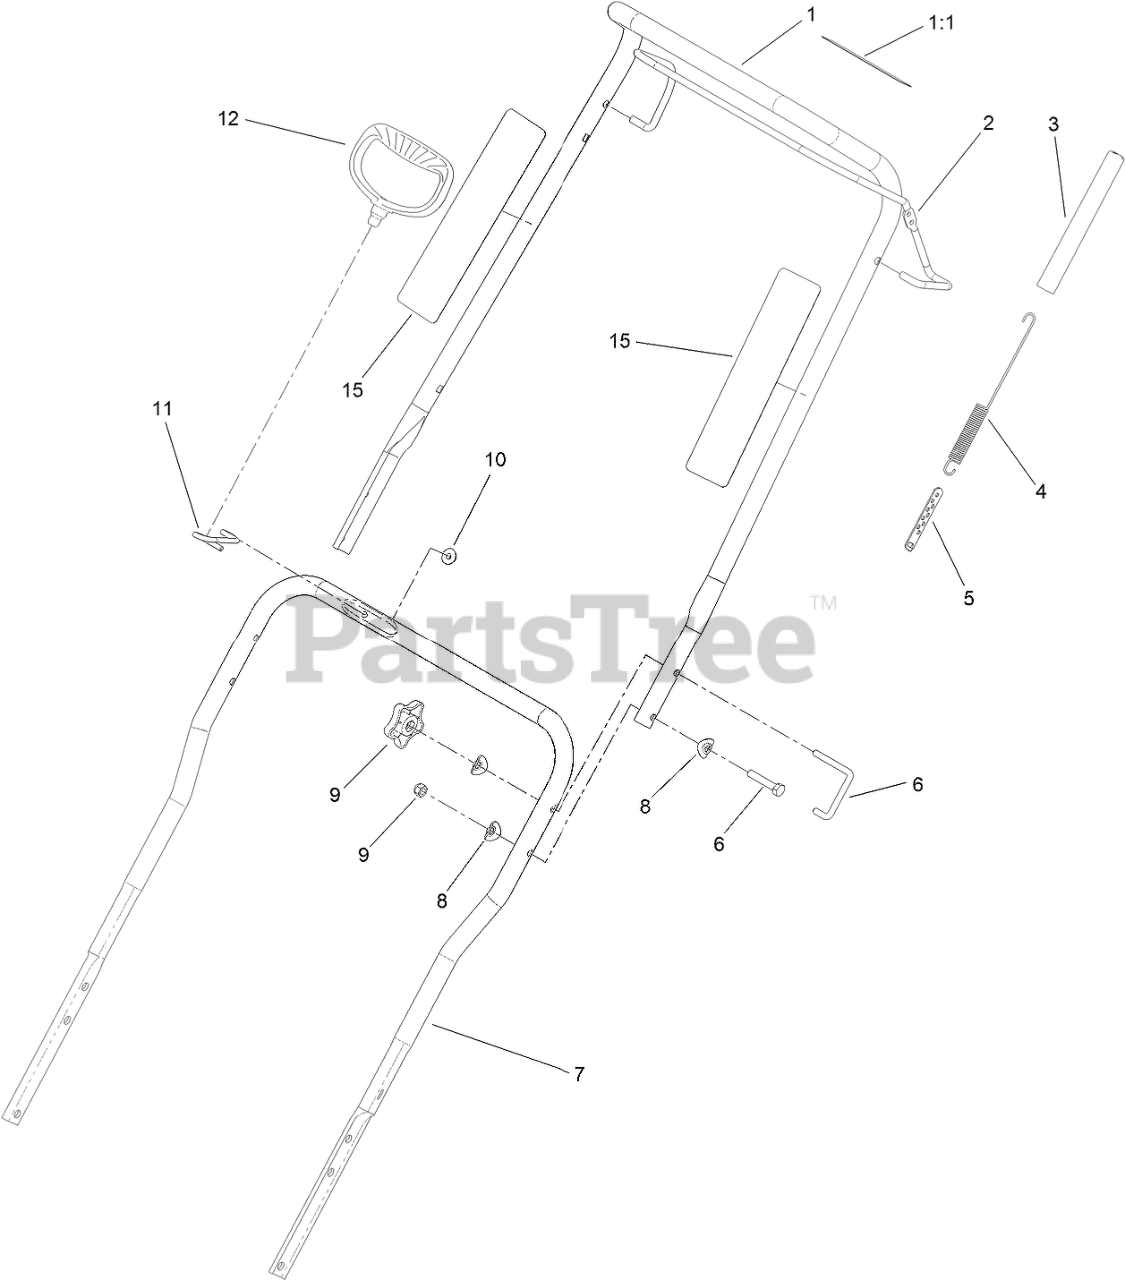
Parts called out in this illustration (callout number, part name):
1	UPPER HANDLE ASM
1:1	DECAL-DRIVE, ROTOR
2	BAIL-CONTROL
3	COVER-SPRING
4	SPRING-EXTENSION, CLUTCH
5	ADJUSTER-CABLE, CLUTCH
6	SCREW-HH
7	HANDLE-LOWER
8	WASHER
9	NUT-LOCK, NI
10	NUT-HEX FLG
11	GUIDE-ROPE
12	HANDLE-RECOIL
15	DECAL-TAPE, REFLECTIVE
